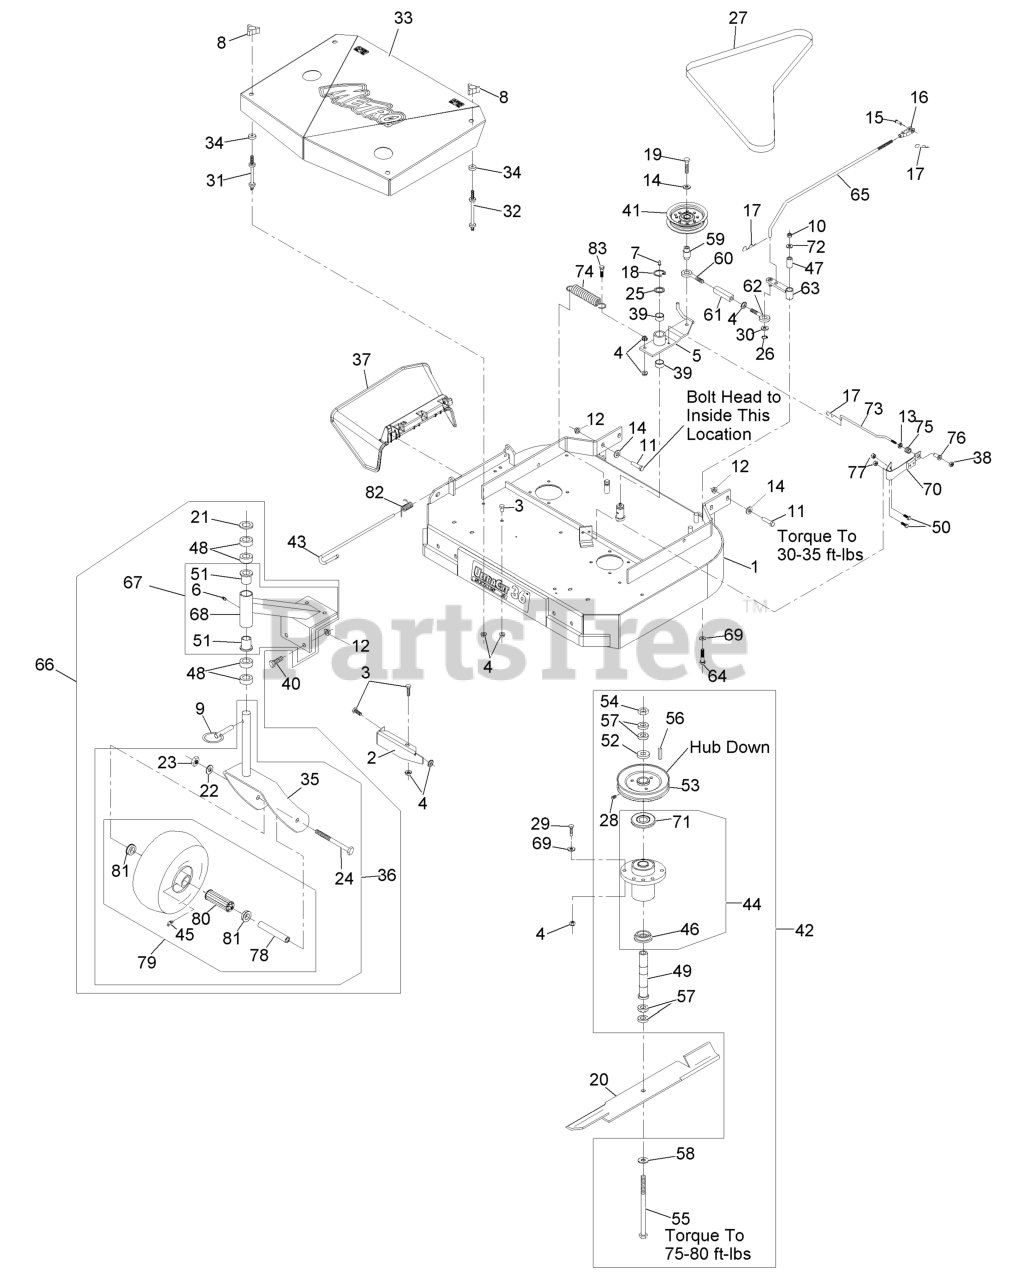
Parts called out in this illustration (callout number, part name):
1	ASM,DECK 36 RIGID
2	BAFFLE-DOGLEG
3	SCREW-HH
5	IDLER ARM ASM
6	FITTING-GREASE
7	FITTING-GREASE
8	KNOB-3 PRONG
10	NUT-LOCK, NI
11	SCREW-HH
12	NUT-HHF, WHIZ
13	RING-PUSH ON
14	WASHER-BELLEVILLE
15	PIN-CLEVIS
16	YOKE-ADJUSTABLE
17	PIN-COTTER
18	RING-RETAINING, EXT
19	SCREW-HH
21	WASHER-FLAT
22	WASHER-LOCK
23	NUT-HH
24	SCREW-HH
25	WASHER-SPINDLE
26	RING-RETAINING, EXT
27	BELT,BLADE METRO 36
28	SETSCREW
29	SCREW-HH
30	WASHER-PLAIN
31	STUD-SHIELD, BELT (SHORT)
32	STUD-SHIELD, BELT (LONG)
33	ASM,SHIELD W/DECALS 36 ME
36	ASM,CASTER/WHEEL
37	CHUTE DEFLECTOR XRK M056
38	NUT-LOCK, NI
39	SLEEVE-BEARING
40	SCREW-HH
42	ASM, CUTTER HOUSING OUTER
43	PIN-CHUTE
44	KIT, CUTTER HOUSING
45	FITTING-GREASE
46	SPACER-GUARD, BOTTOM
47	TUBE-PIVOT
48	SPACER-CASTER
49	TUBE-SPINDLE, SHORT
50	SCREW-HH
51	BEARING-FLANGED
52	WASHER-RETAINER, SHEAVE
54	NUT-HEX
55	SCREW-CAP, HH
58	WASHER-SPRING
59	BUSHING-ENGAGEMENT
60	EYEBOLT-THREAD, LH
61	BODY-TURNBUCKLE
62	EYEBOLT-THREAD, RH
63	ARM-ASSIST, 32/36
64	SCREW-HH
65	ARM-ASSIST, LINKAGE
67	ASM,CSTR SUPPORT W/WEIGHT
69	WASHER-SPRING
70	PAD AND SPRING ASM
71	GUARD-BEARING, TOP
72	WASHER-FLAT
73	ROD-BRAKE
74	SPRING-EXTENSION
75	SPRING-COMPRESSION
76	SPACER-FLANGED
77	NUT-LOCK, NI
79	KIT, SP CASTER WHEEL REPL
80	BEARING
81	BUSHING
82	SPRING, TORSION
83	SCREW-HH, SPECIAL
